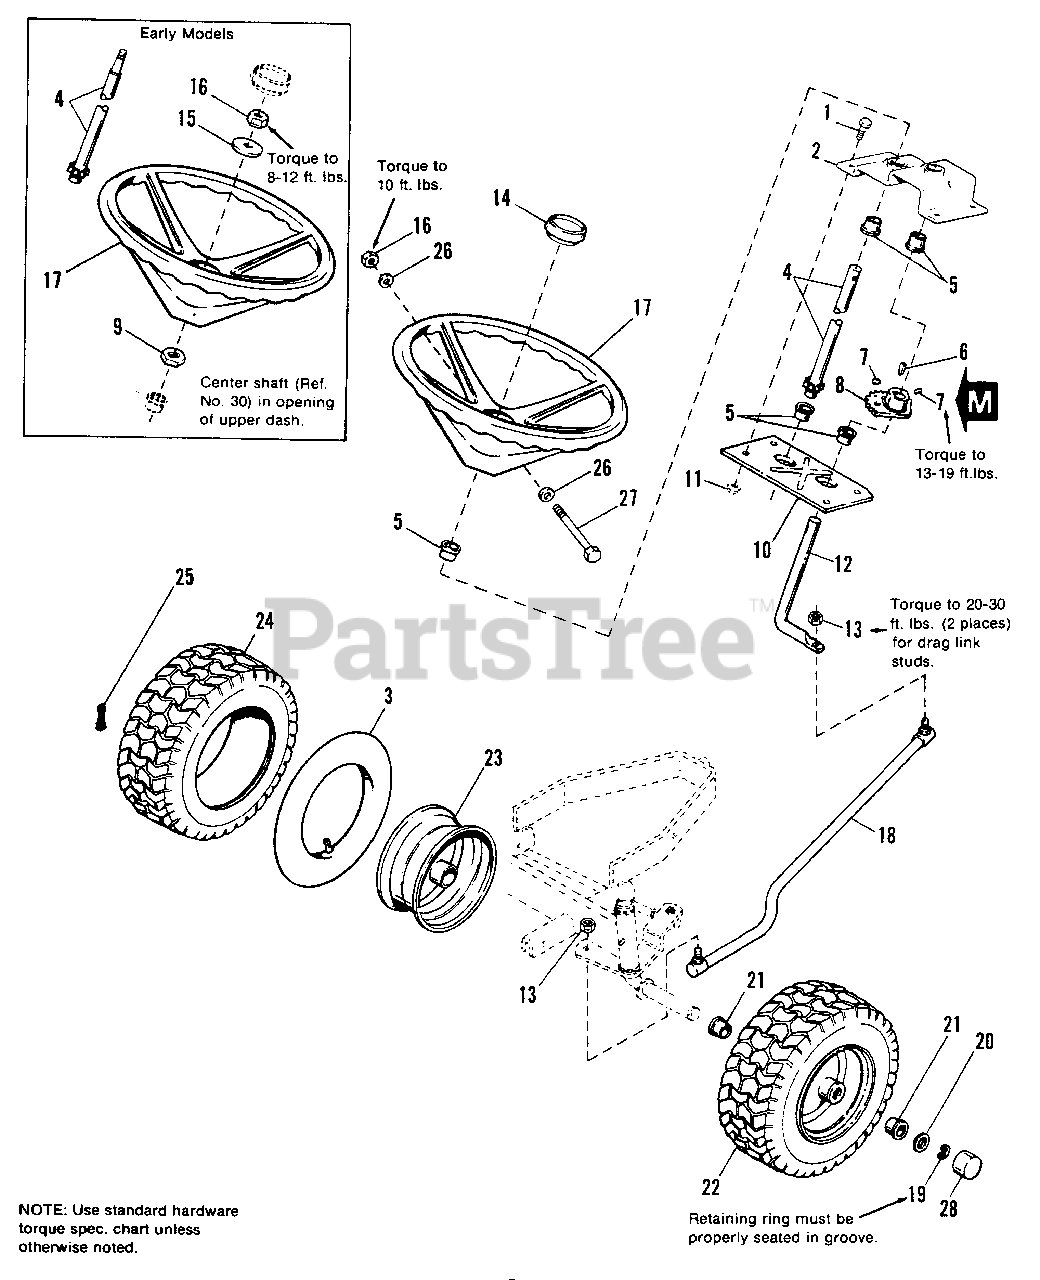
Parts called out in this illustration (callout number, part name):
1	CAPSCREW, 5/16-18 x 3/4
2	TOP PLATE, Steering
3	TUBE (For Service Only)
4	SHAFT ASSY., Steering
5	BUSHING (Qty. 4 used on earlier models)
7	SETSCREW, 5/16-18 x 1/2, Gr. 8
8	GEAR, Steering
9	WASHER, Hex
10	BASE PLATE, Steering
11	LOCKNUT, Flange, Whiz, 5/16-18
12	ROD, Steering
13	LOCKNUT, Center, 3/8-24
14	CAP, Steering Wheel
15	WASHER, Compression
16	LOCKNUT, Hex, 5/16-18
17	WHEEL, Steering
19	"E" RING, Ext., 3/4
20	WASHER (Mfg. No. 1690759 only)
20	WASHER (Mfg. No. 1690846 only)
22	WHEEL & TIRE ASSY., 13 x 5.00-6 (Mfg. No. 1690759 only)
22	WHEEL & TIRE ASSY., 15 x 6.00-6 (Mfg. No. 1690846 only)
23	WHEEL, w/o Bearings (Mfg. No. 1690759 only)
23	WHEEL, w/o Bearings (Mfg. No. 1690846 only)
24	TIRE, (Carlisle) 15 x 6.00-6 (Mfg. No. 1690846 only)
24	TIRE (Carlisle) 13 x 5.00-6 (Mfg. No. 1690759 only)
25	STEM, Valve
26	WASHER, Plain, 5/16
27	BOLT, Hex, 5/16-18 x 3-1/2
28	CAP, Hub, Threaded (Mfg. No. 1690846 only)
